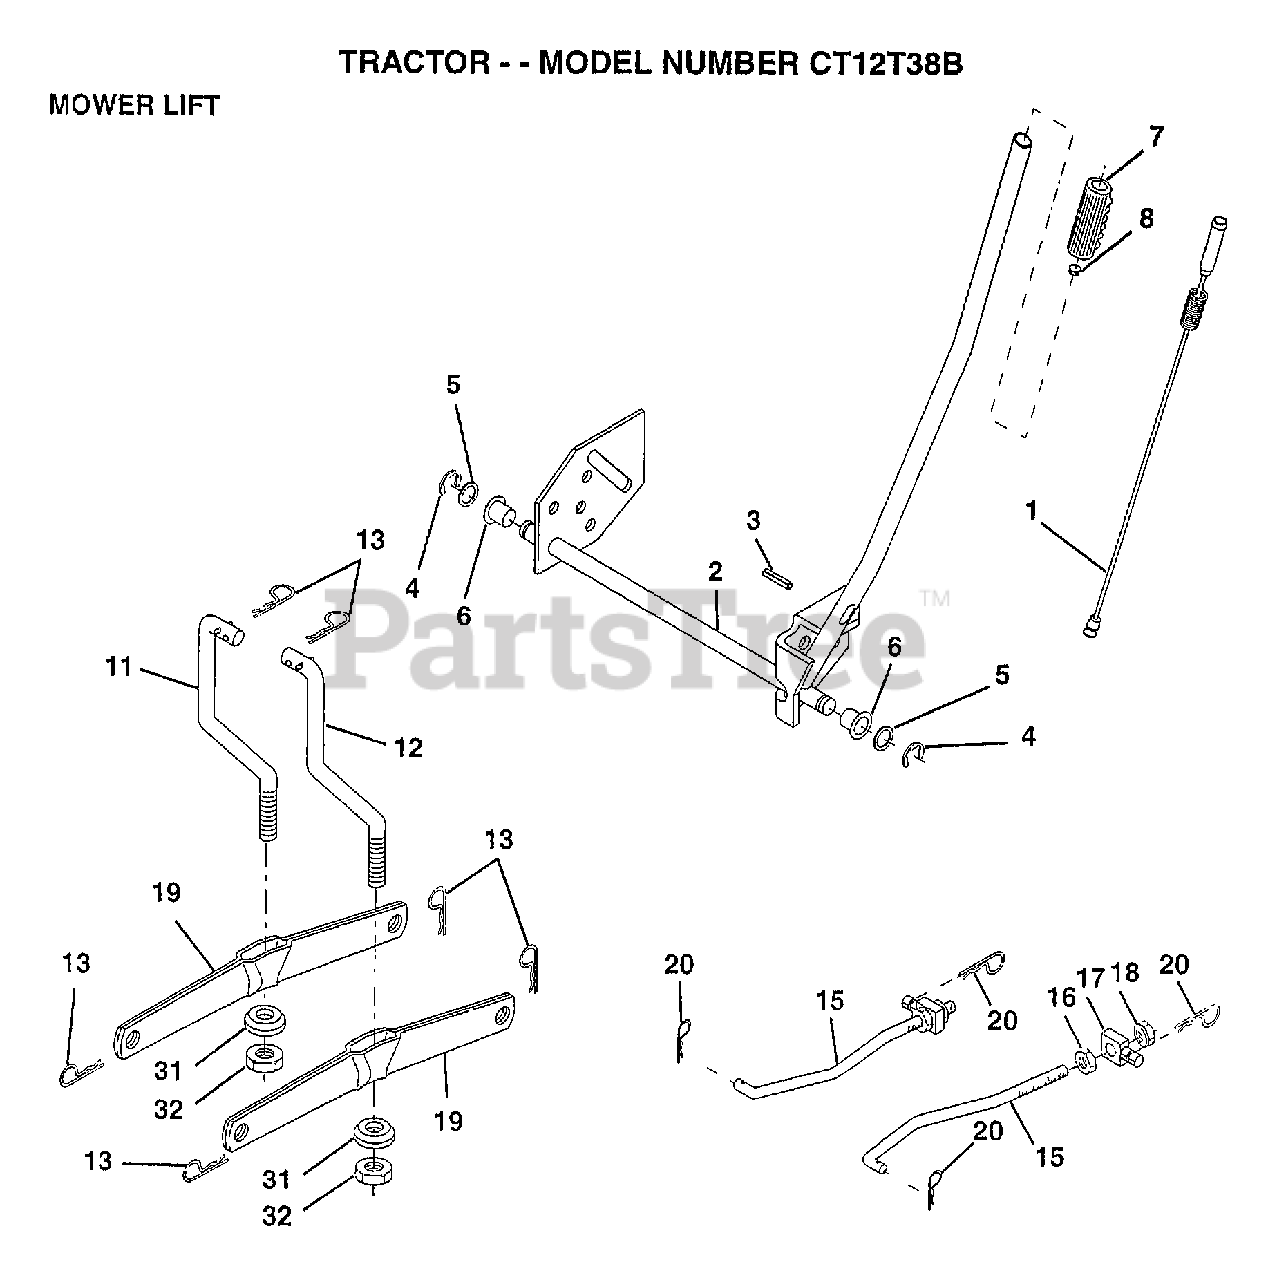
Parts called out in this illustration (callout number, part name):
1	WIRE ASM W.SPRING
2	SHAFT ASM.LIFT
3	PIN-GROOVE LT
5	WASHER
6	NYLON BEARING
7	GRIP
15	LINK.FRONT
16	NUT
17	TRUNION
18	NUT.LK.W/WSH.1/2.
19	ARM SUSP REAR
20	RETAINER.SPRING
31	BEARING PVT LH
32	NUT.CROWNLOCK.3/8
